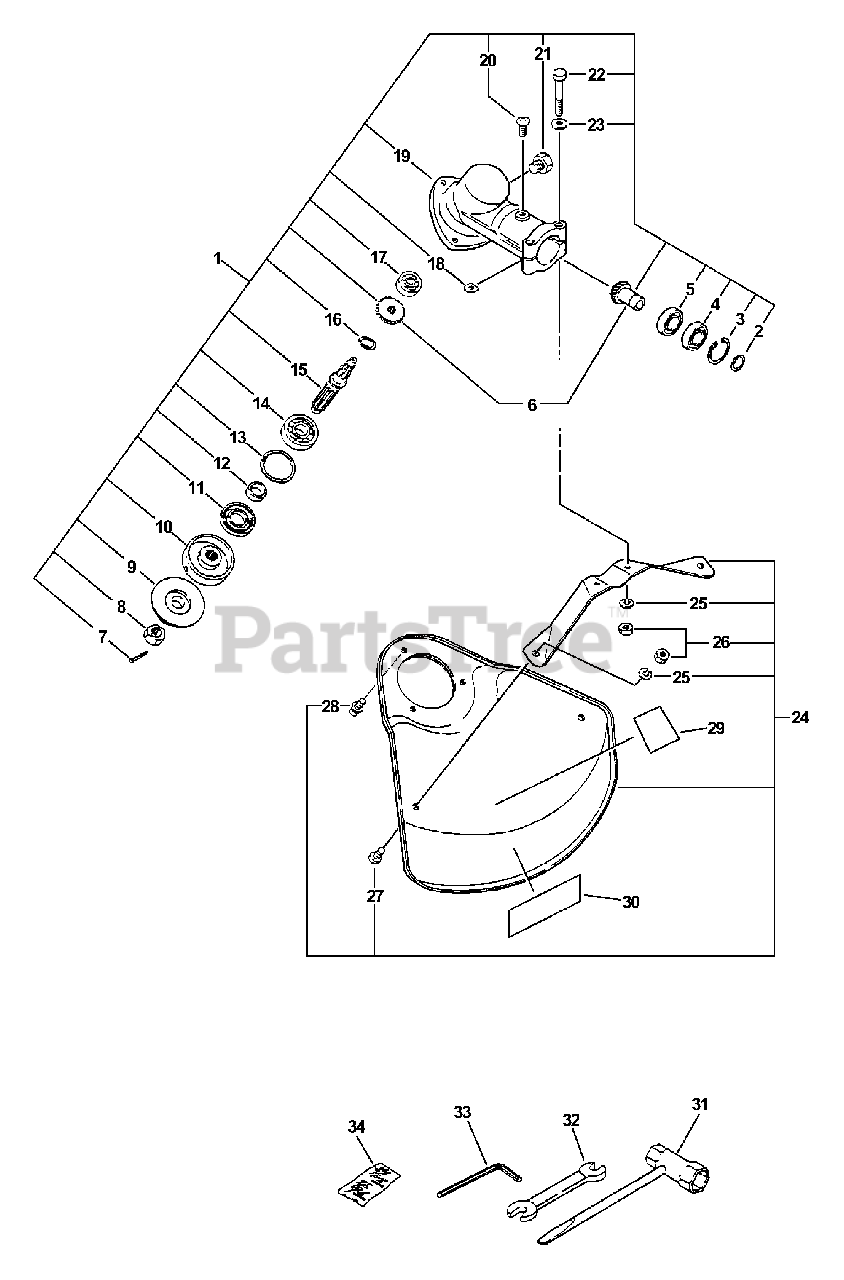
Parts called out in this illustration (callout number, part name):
1	GEAR CASE ASSY
2	RING, SNAP Ø10
3	RING, SNAP Ø22
4	BEARING, BALL 6900Z
5	BEARING, BALL 6900
6	GEAR SET
7	PIN, COTTER 2×22
9	PLATE, ADAPTOR - LOWER
10	PLATE, ADAPTER - UPPER
11	SEAL, OIL 22
12	RING, SNAP Ø32
13	SPACER 11.8×15×9
14	BEARING, BALL - 6201 C3
15	SHAFT, GEAR
16	RING, SNAP Ø12
17	BEARING, BALL 609
19	HOUSING, GEAR CASE
20	SCREW 5×10
21	BOLT 8×8 SP
22	BOLT 5×35 SP
23	WASHER, FLAT 5.5×10×0.8
24	SHIELD ASSY
25	WASHER, SPRING 5
26	NUT M5
27	SCREW 5×8
28	SCREW 5×10
29	LABEL, ECHO
30	LABEL, DANGER
31	T-WRENCH 17x-19 L200
32	SPANNER 8×10
33	WRENCH, ALLEN 3 MM
34	PIN, COTTER 2×22 (PKG. OF 10)
